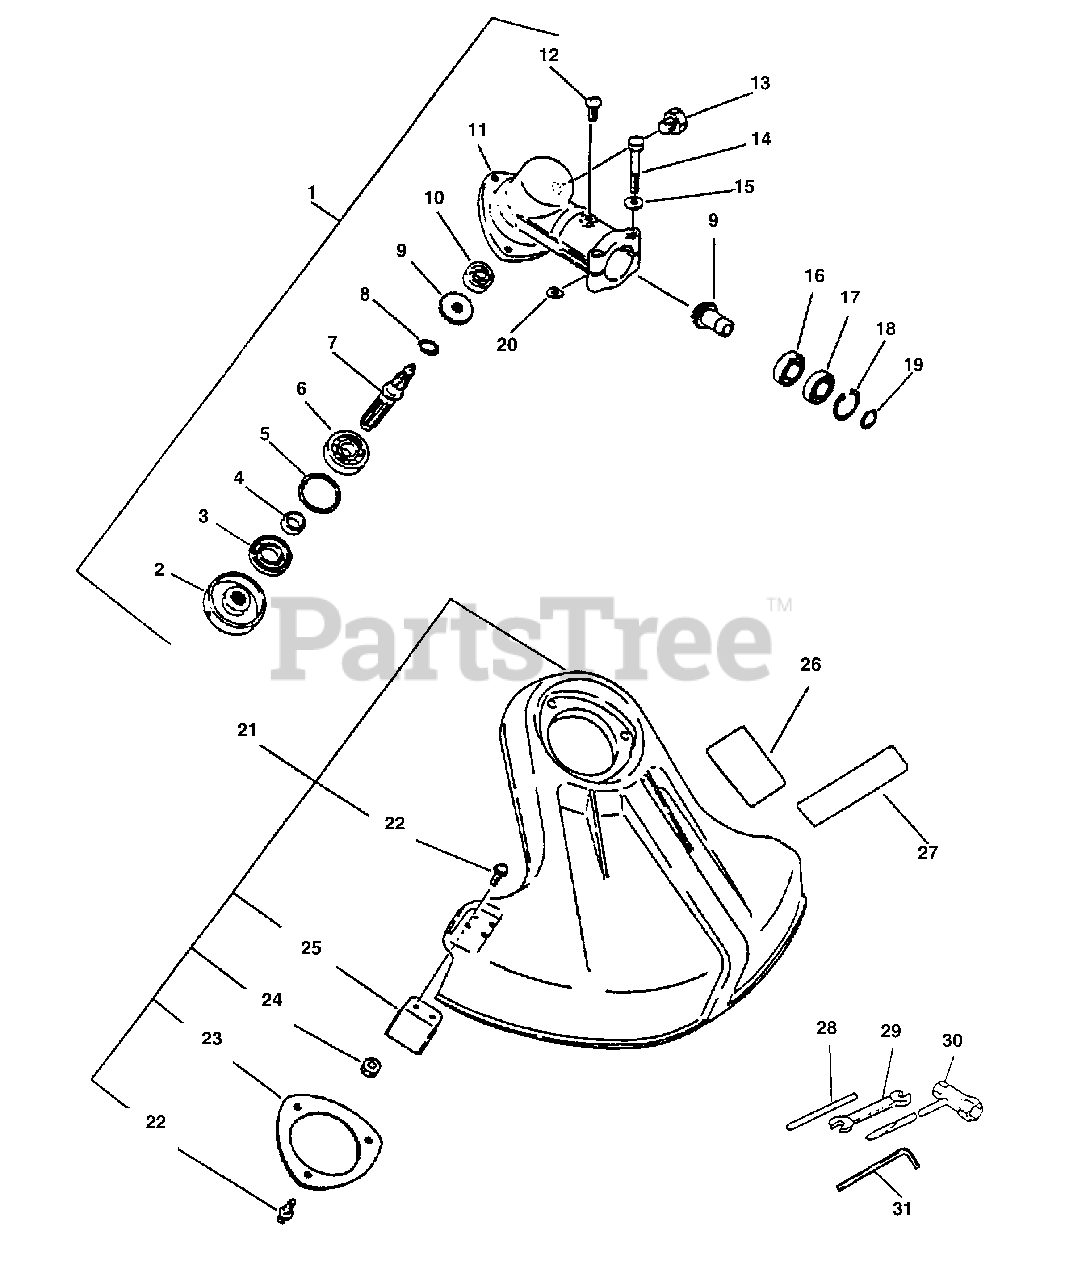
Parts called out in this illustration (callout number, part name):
1	GEAR CASE ASSY
2	PLATE, ADAPTOR - UPPER
3	SEAL, OIL 22
4	SPACER 11.8×15×9
5	RING, SNAP Ø32
6	BEARING, BALL - 6201 C3
7	SHAFT, GEAR
8	RING, SNAP Ø10
9	GEAR SET
10	BEARING, BALL 609
11	HOUSING, GEAR CASE
12	SCREW 5×10
13	BOLT 8×8 SP
14	BOLT 5×35 SP
15	WASHER, FLAT 5.5×10×0.8
16	BEARING, BALL 6900
17	BEARING, BALL 6900Z
18	RING, SNAP Ø22
19	RING, SNAP Ø12
21	DEBRIS SHIELD KIT
22	SCREW 5×16
23	PLATE, SHIELD Ø49.5 MM
24	NUT M5
25	CUTTER, LINE
26	LABEL, CAUTION
27	LABEL, ECHO
28	TOOL, LOCKING 5×120 MM
29	SPANNER 8×10
30	T-WRENCH 17x-19 L200
31	WRENCH, ALLEN 3 MM
